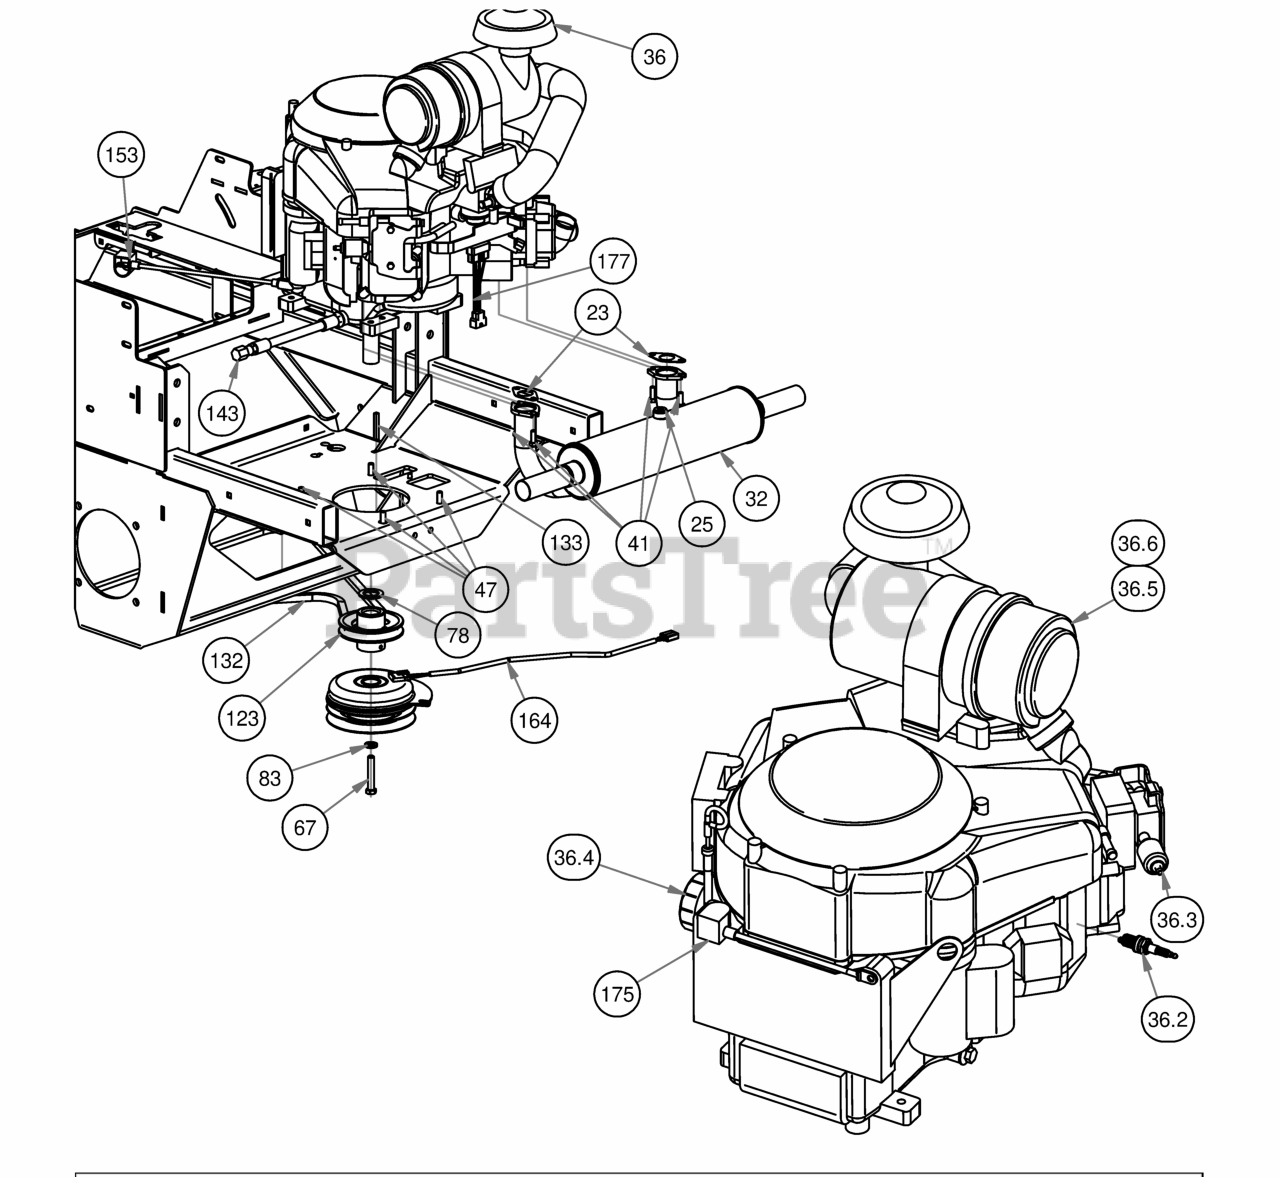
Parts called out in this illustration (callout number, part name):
23	Exhaust Gasket for 23 Vanguard
25	O2 Sensor Plug
32	Muffler for 36Hp Vanguard
36	993cc Vanguard Engine
36.2	Spark Plug
36.3	Universal Inline Fuel Filter
36.4	Oil Filter
36.5	Canister Air Filter- Outer
36.6	Canister Air Filter- Inner
41	Torx Bolt-Exhaust
47	3/8 x 1 1/8 bolt
67	7/16" x 2 1/2" Hex Bolt
78	1 1/8" Flat Spacer
83	7/16" Lock Washer
123	4 3/4 Motor Pulley
132	2019 Rebel Pump Belt
133	1/4 x 2 Square key Stock
143	14 mm Oil drain Hose 993cc Vanguard
153	14" Red Battery Cable-Base Outlaw
163	Clutch Assembly
164	Clutch Pigtail
165	2019 Rigid Frame
175	Starter Cable
177	2019 Harness Adaptor - 36 Vanguard Carberated
